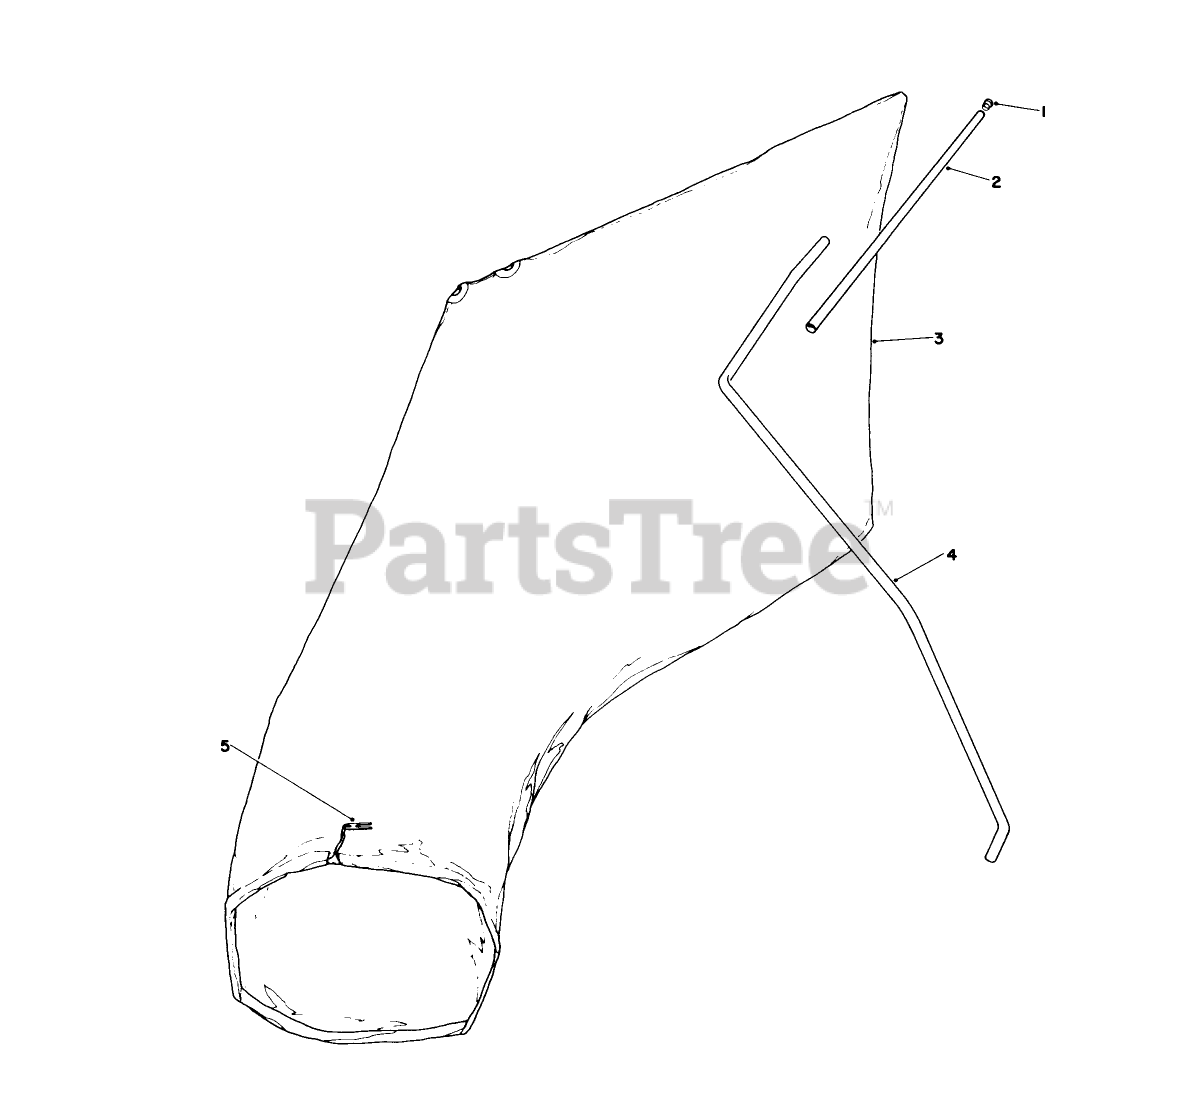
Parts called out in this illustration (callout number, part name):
2	BAG HANGER TUBE
3	Bag (Incl. Ref. #5)
4	HANGER ROD
5	BAG CORD FASTENER
